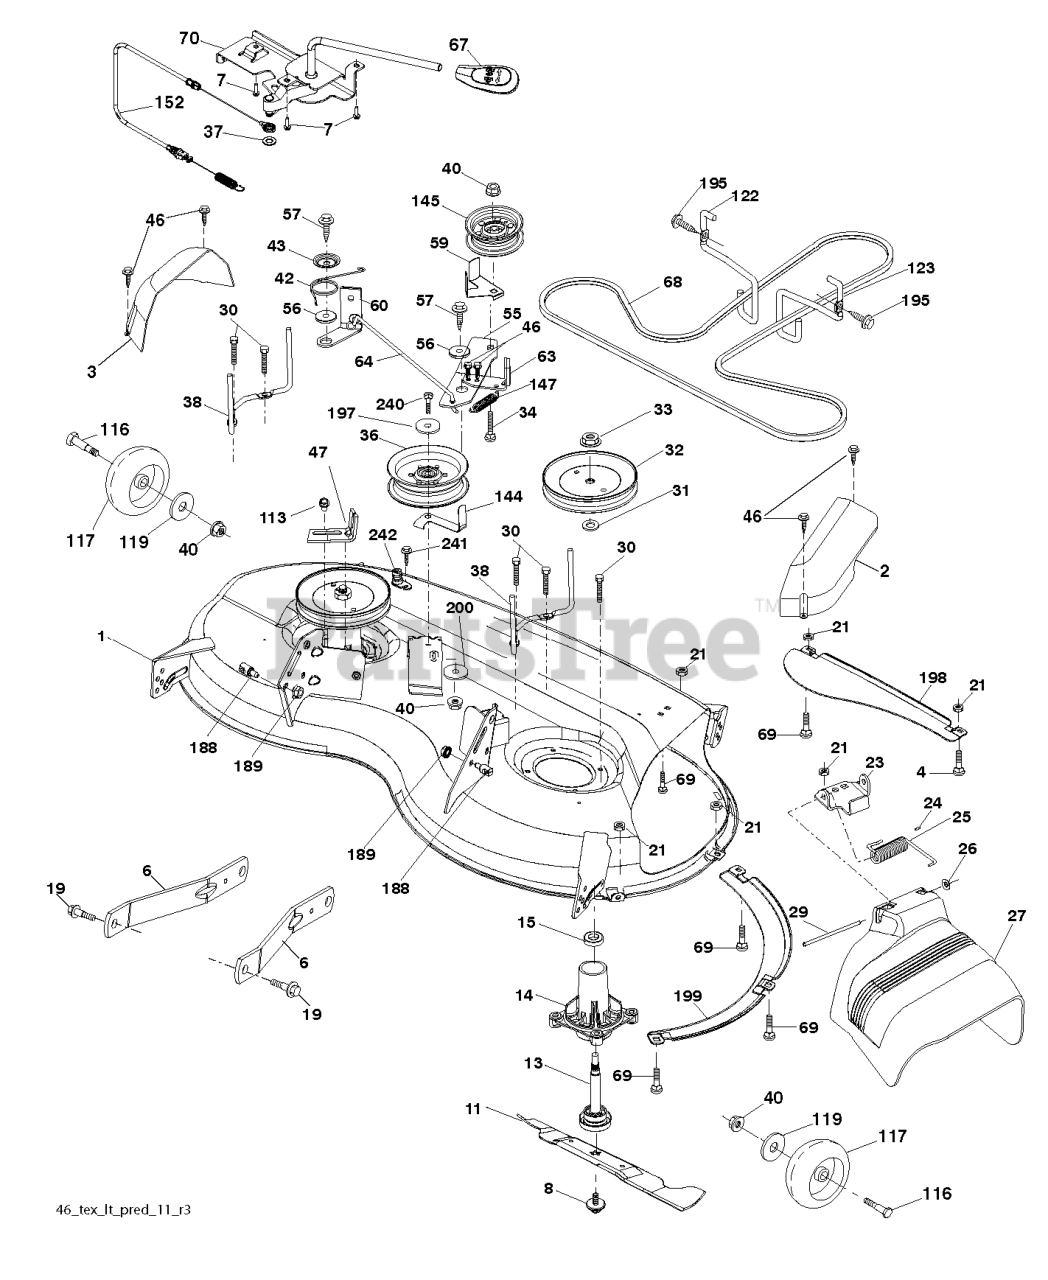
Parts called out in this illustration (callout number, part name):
1	DECK.WELDMENT.46.2GA.WHLS.GRAY
2	COVER.MANDREL.RH.46"
3	COVER.MANDREL.LH.46"
6	ARM.SUSPENSION.MOWER.R
7	SCREW.#10 X 0.750.BOS
8	BOLT.WASHER.ASM.7/16-2
11	BLADE.MOWER.46".HI.LIFT
13	SHAFT.ASM.MDRL.N/GREASE.38
14	RP.HOUSING.MANDREL.4PT.
19	BOLT.SHOULDER
21	LOCKNUT
23	BRKT.DEFLECTOR.38"2005+
24	CAP-SLEEVE LT
25	SPRING.TORSION.DEFLECT
26	NUT PUSH M
27	SHIELD.DEFLECTOR.MOWER.46"BLAC
29	ROD.HINGE
30	SCREW, WASHER HEAD
31	WASHER.SPACER.MANDREL
32	PULLEY.MANDREL.5.438.PD
33	NUT.FLANGE.LOCK.TOP
34	BOLT.3/8-16X1.50
36	PULLEY.IDLER.2006
37	WASHER
38	KEEPER.BELT.MANDREL.PULLEY
40	NUT LOCK FLG 3/8-16 UNC
42	SPRING.TORSION.BRAKE
43	SRPING.TORSION.RETAINE
46	SCREW.1/4-20X5/8
47	BRKT.CLUTCH.CABLE
55	IDLER.ARM
56	SPACER.RETAINER
57	SCREW 3/8-16X1
59	GUARD, BELT
60	ARM BRAKE MOWER RH 38"
63	ARM BRAKE MOWER
64	LINKAGE BRAKE
67	HANDLE.CLUTCH.CABLE.LT
68	V-BELT
69	BOLT
70	CLUTCH.ASM.MANUAL.YT.PREDATORQ
113	BOLT.5/16HEX.WHS.HD
116	BOLT.SHOULDER.3/8-16X3-5/8.
117	RP WHEEL. GUAGE RALLY
119	WASHER
122	KEEPER BELT ENGINE LH
123	KEEPER BELT RH
144	KEEPER.BELT.MOWER
145	PULLEY.IDLER.48"PRIMARY
147	SPRING RETURN
152	CABLE.CLUTCH.CABLE.W/SPRING
188	STUD.FASTNER.W/ANTI-ROTATE
189	NUT LOCK HEX FLANGE 5/16-18
195	SCREW, 3/8-16X3/4
197	WASHER
198	BAFFLE CENTER FRONT
199	BAFFLE FRONT RH
200	WASHER.13/32 X 1 X 1/2.11GUARD
240	BOLT-HEX EAK
241	SCREW.TT.#10-32X.5.3/8.FLANGE
242	PORT.WASHOUT
